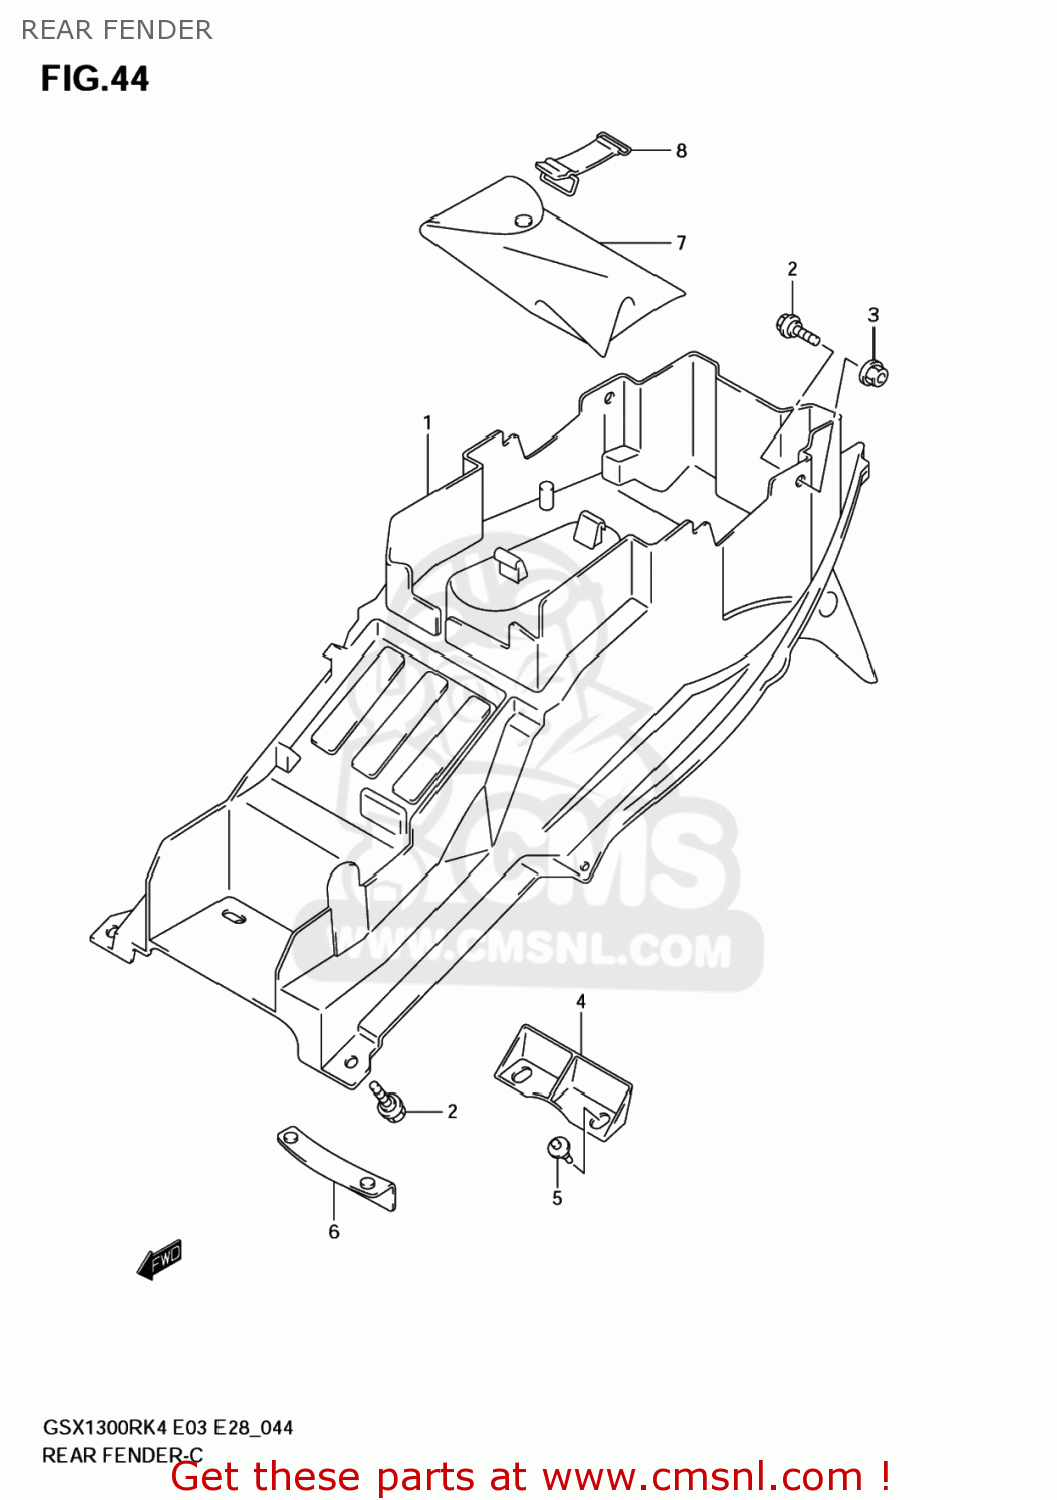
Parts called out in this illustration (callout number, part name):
1	FENDER,RR
2	BOLT(6X16)
3	NUT
4	MUDGUARD,RR FENDER
5	CLIP
6	MUDGUARD,RR FENDER FR UPR
7	TOOL ASSY
8	BAND
